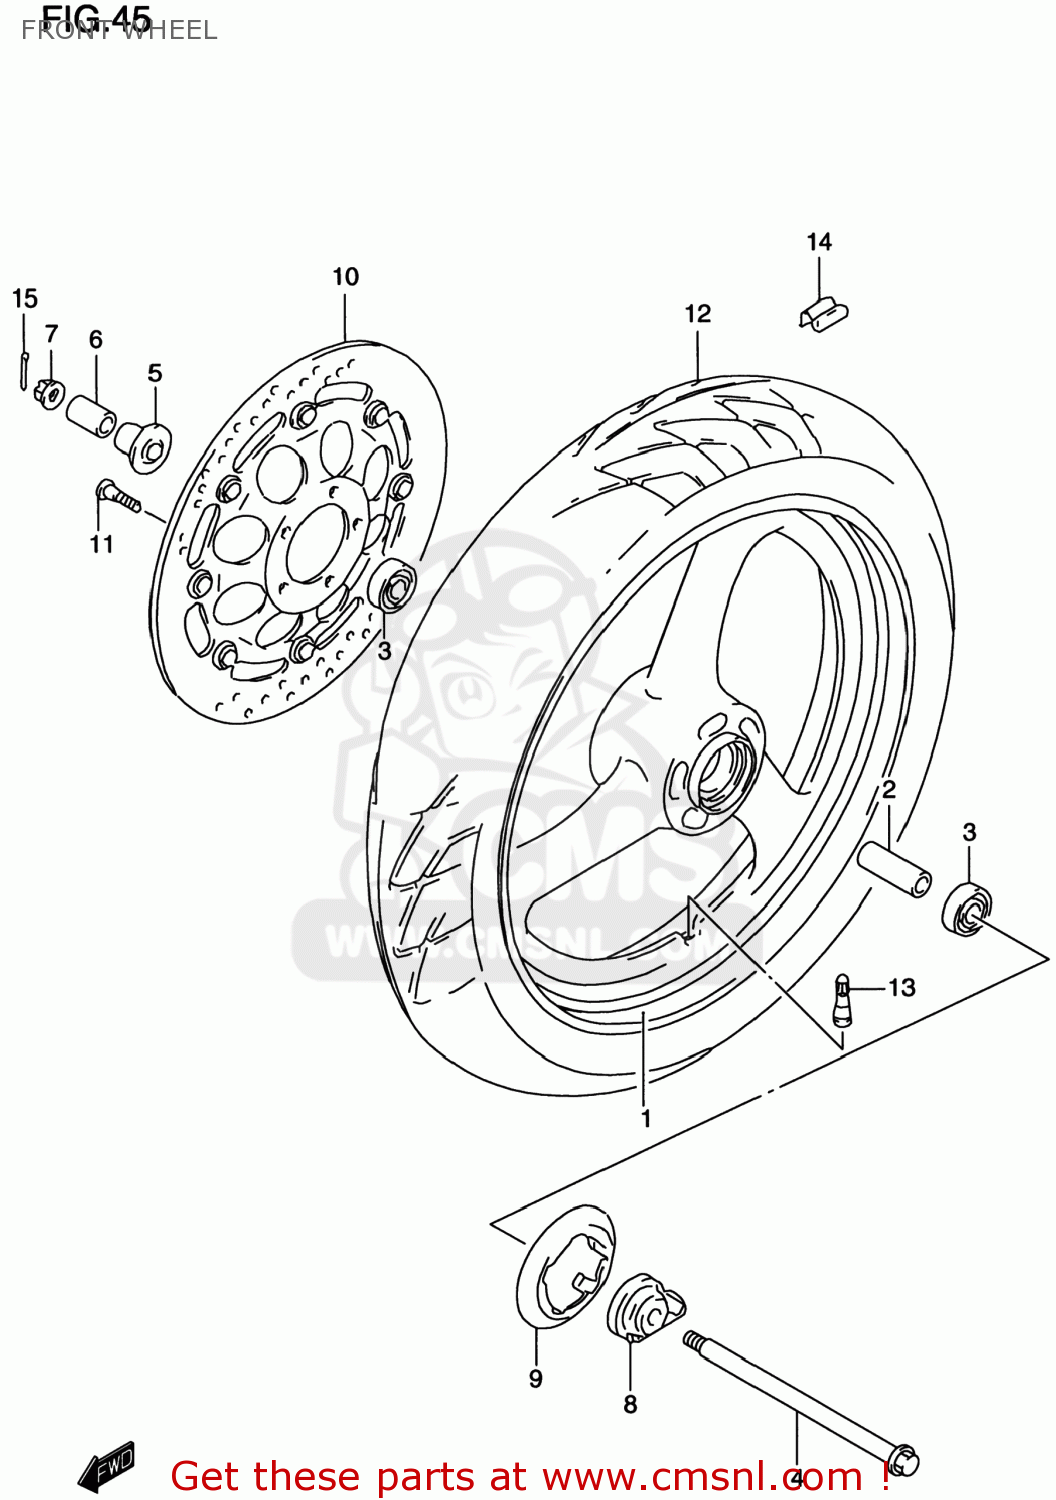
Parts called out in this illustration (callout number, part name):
1	WHEEL,FRONT (MT3.00X17)
2	SPACER(15.3X21.7X63)
3	BEARING
4	AXLE,FR
5	SPACER,FR AXLE
6	SPACER,FR AXLE,R
7	NUT
8	BOX ASSY,SPEEDOMETER GEAR
9	COVER,FRONT HUB,LEFT
10	DISC,FR BRAKE,R
11	BOLT 8X33
12	TIRE,T/L(110/70-17 54H)
13	VALVE ASSY,WHEEL RIM(TR412)
14	BALANCER,WHEEL (10G)
15	COTTER PIN
